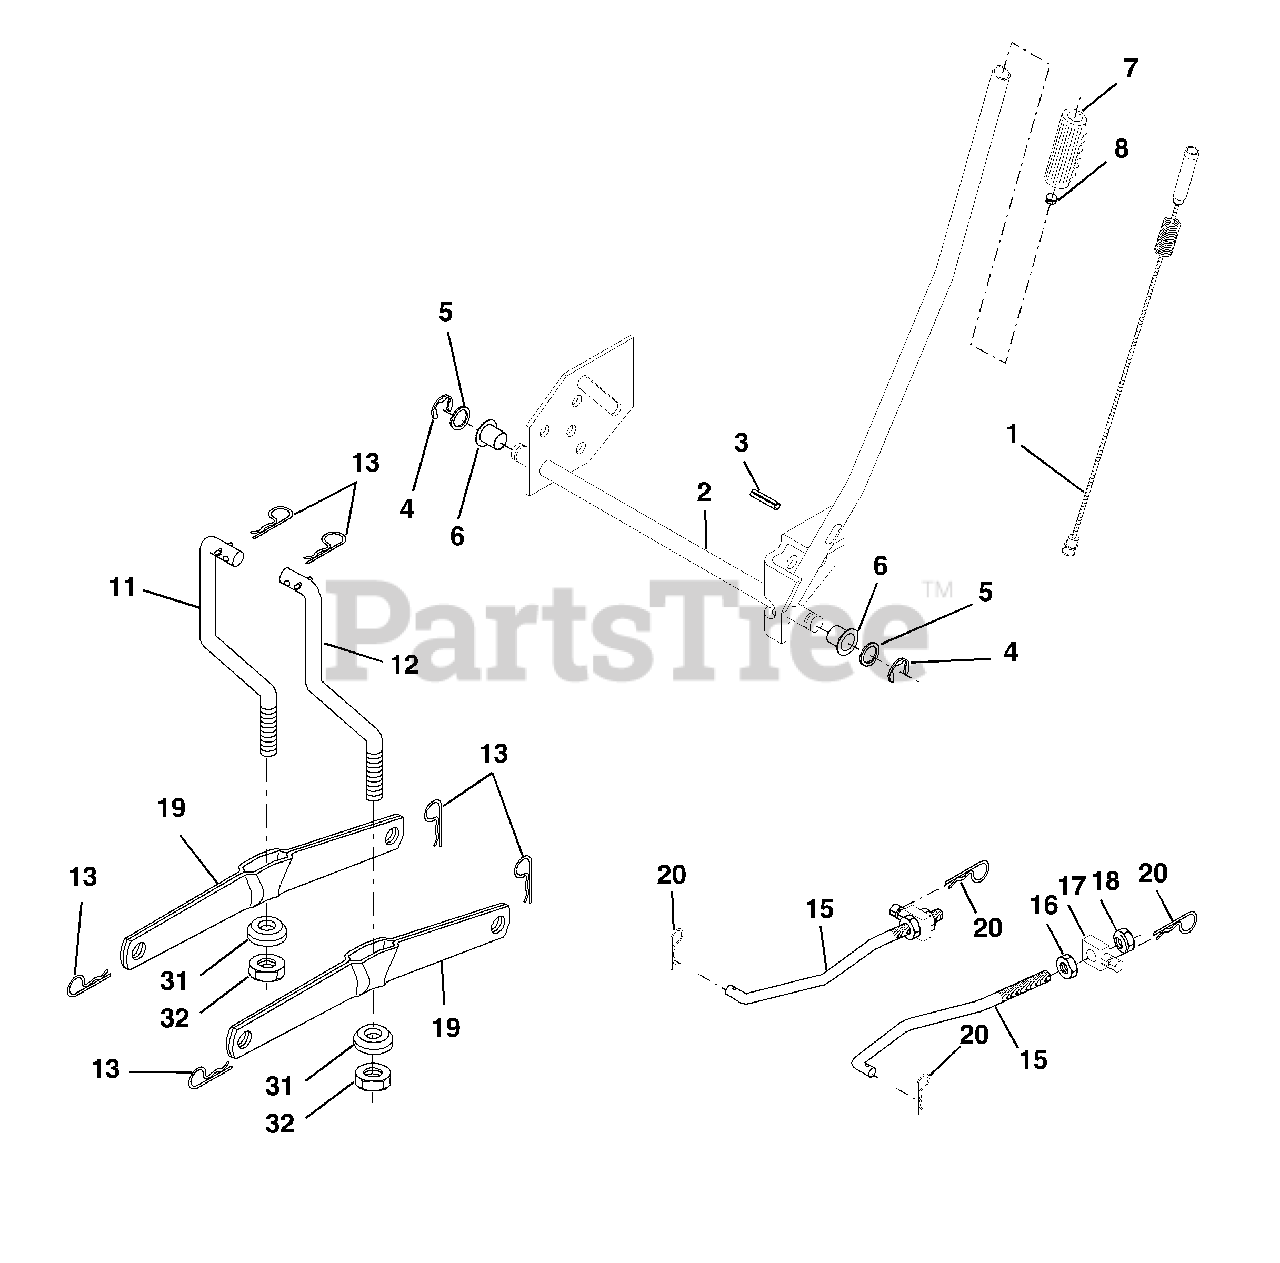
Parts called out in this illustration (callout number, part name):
1	Wire Asm Inner/Sprg w/plunger
2	Shaft Asm Lift RH
3	Pin Groove 1 500 Zinc
4	E Ring #5133-62
5	Washer 21/32 X 1 X 21 Ga
6	Bearing Nylon Blk 629 Id
7	Grip Handle Bicycle Matte Blk
8	Button Plunger Black
11	Link Lift LH Fixed Length
12	Link Lift RH Fixed Length
13	Retainer Spring
15	Link Front
16	Nut Jam Hex 1/2-13 Unc
17	Trunnion
18	Nut Lockw/Wsh 1/2-13 Unc
19	Arm Suspension Rear
20	Retainer, Spring
31	Bearing Pvt Lift
32	Nut Crownlock 3/8-24
